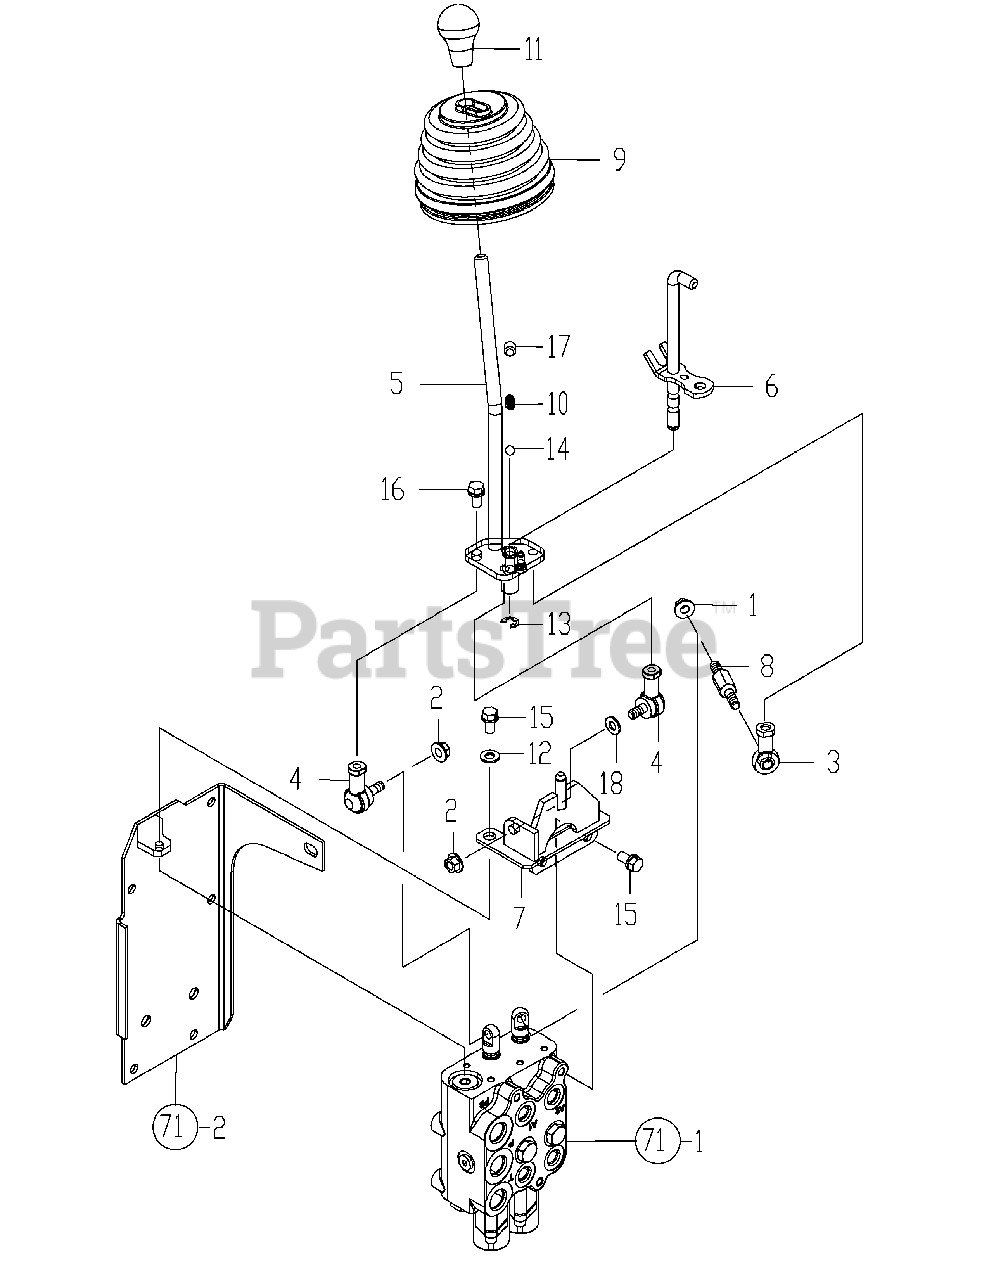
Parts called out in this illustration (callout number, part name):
5	LEVER CMP, SCV
7	BKT CMP, SCV LEVER
8	BOLT, SCV LEVER
9	BOOTS, SCV LEVER
17	SCREW, 10 X 10
